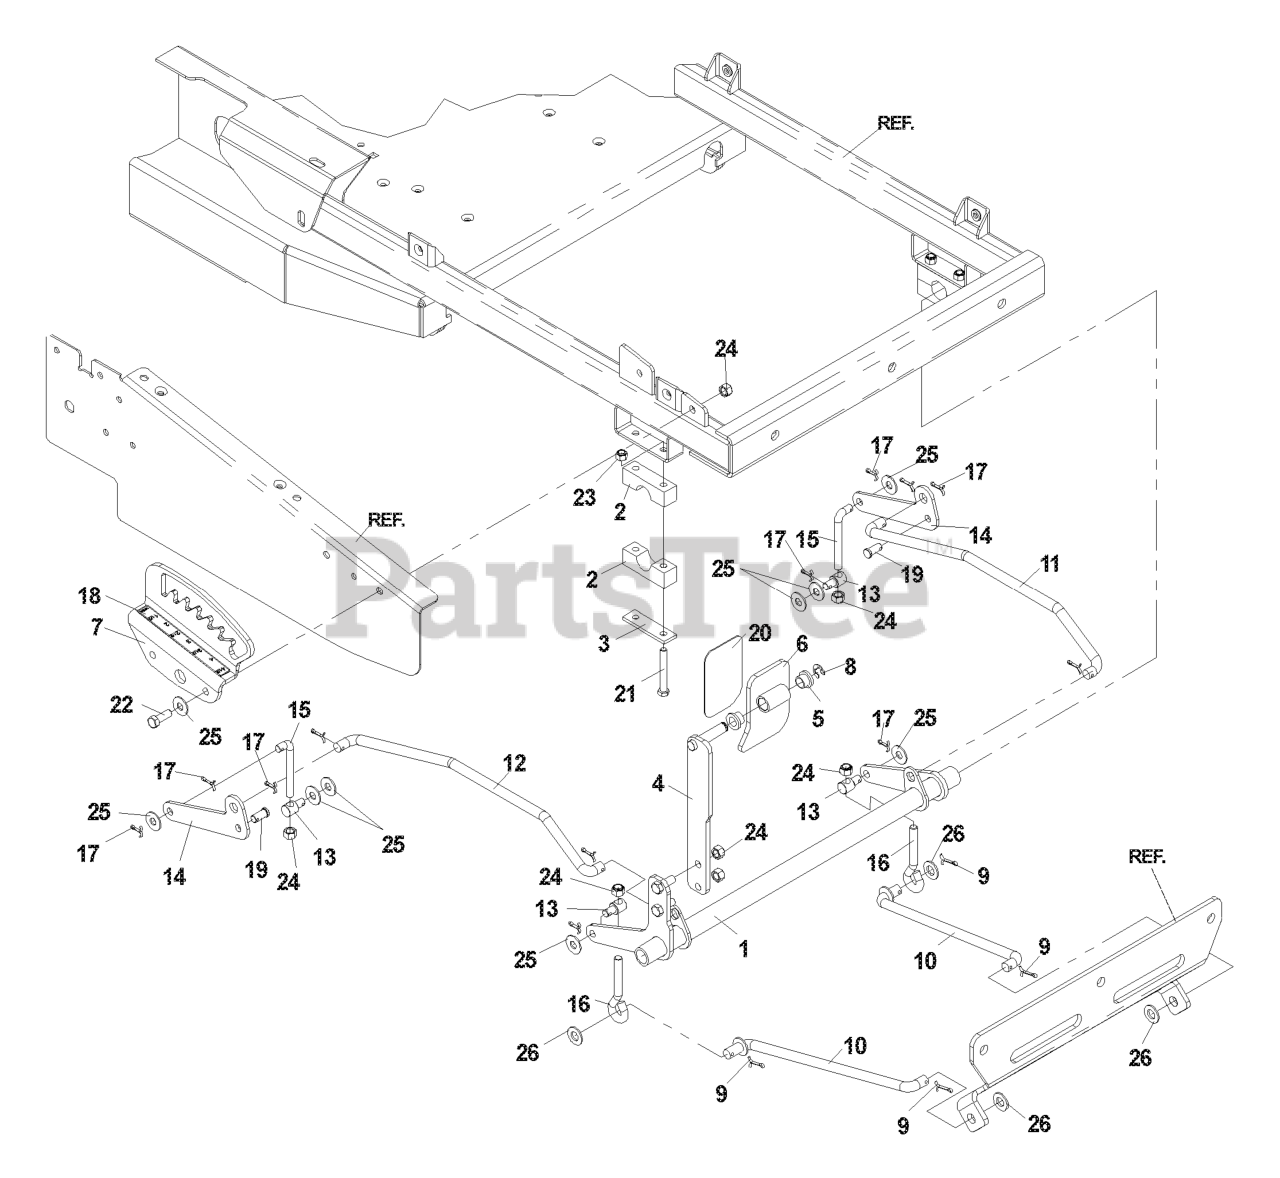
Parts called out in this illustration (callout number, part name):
1	CROSS SHAFT WELDMENT
2	PILLOW BLOCK
3	REINFORCEMENT BAR
4	LIFT ARM WELDMENT
5	BUSHING, FLANGED NYLON
6	FOOT PEDAL WELDMENT
7	HEIGHT PLATE
8	E-RING 1/2 (2 2)
9	COTTER PIN
10	STRUT LINKAGE
11	LIFT LINKAGE-LH
12	LIFT LINKAGE-RH
14	REAR BELLCRANK
15	LIFT LINKAGE
16	EYE BOLT
17	RP_COTTER PIN 1/8 X 3/4
18	DECAL, CUTTING HEIGHT
19	CLEVIS PIN
21	BOLT 5/16C X 2 1/2
22	HCS 3/8C X 1 1/4 GR5
23	NUT 5/16 NYLOC
24	NUT 3/8-16 NYLOC
25	WASHER 3/8 FLAT
26	WASHER 1/2" FLAT
